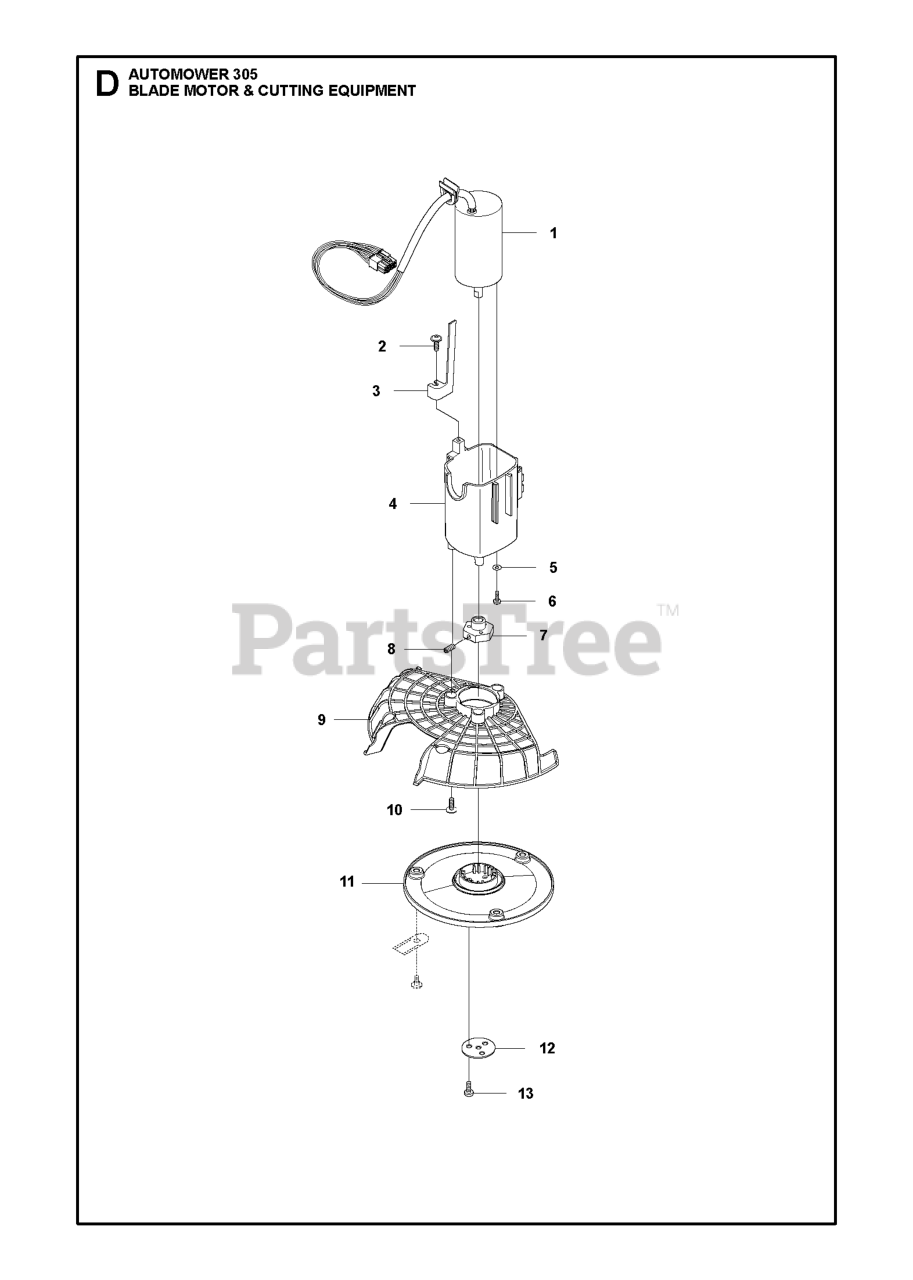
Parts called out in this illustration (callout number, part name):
2	SCREW 14MM
3	HEIGHT INDICATOR
4	MOTOR HOUSING
6	SCREW ITXPANM M4X12 8.8 ZP-BC
7	HUB CUTTING MOTOR
8	SCREW IHSETM M5X10 8.8 ZP-BC
10	SCREW 14MM
11	CUTTING DISC
12	WASHER DRIVE WHEEL
13	SCREW ITXPANM M4X12 8.8 ZP-BC
